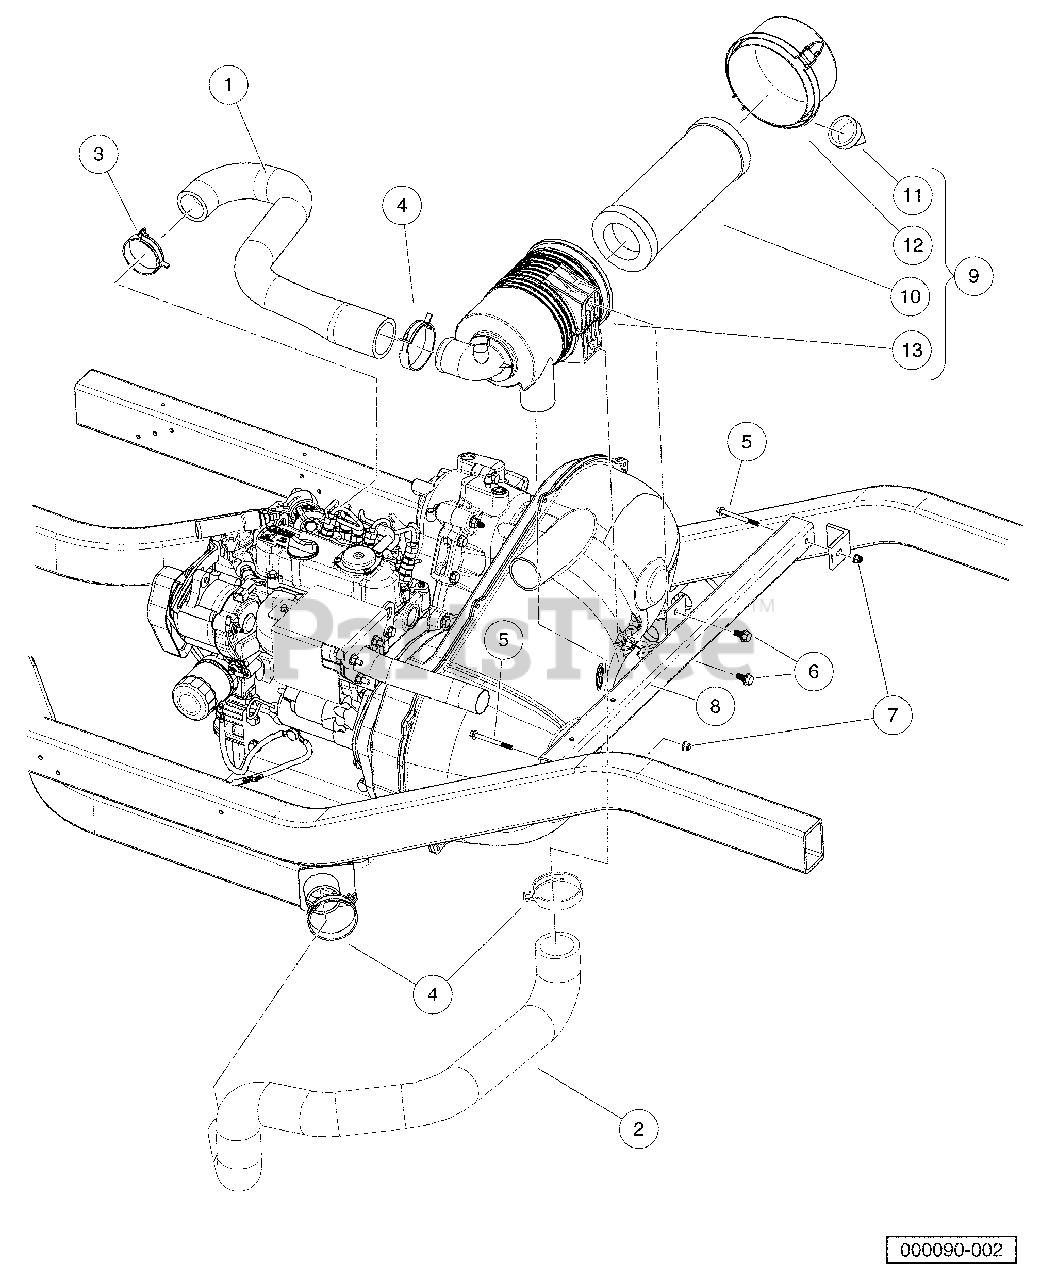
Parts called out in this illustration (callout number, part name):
1	Hose, Intake, D722
2	Hose, Intake, Primary
3	Clamp, Hose, Ctb 55mm
4	Clamp, Hose, Ctb 64mm
5	Bolt, M 6 X 1.0 X 65 Hex, Flange, Head, Black
6	Bolt Flanged Head, M8 X1.25x 16 with Loctite
7	Nut Flg, M6 X 1.0 Nylon
8	Weldment, Support, Air Cleaner
9	Filter, Air, Canister, W/labe
10	Element, Filter, Air, 5 In
11	Valve, Evacuator, Filter Air
12	Cap, Latch Lock, Filter, Air
13	Body, Canister, Filter, Air
